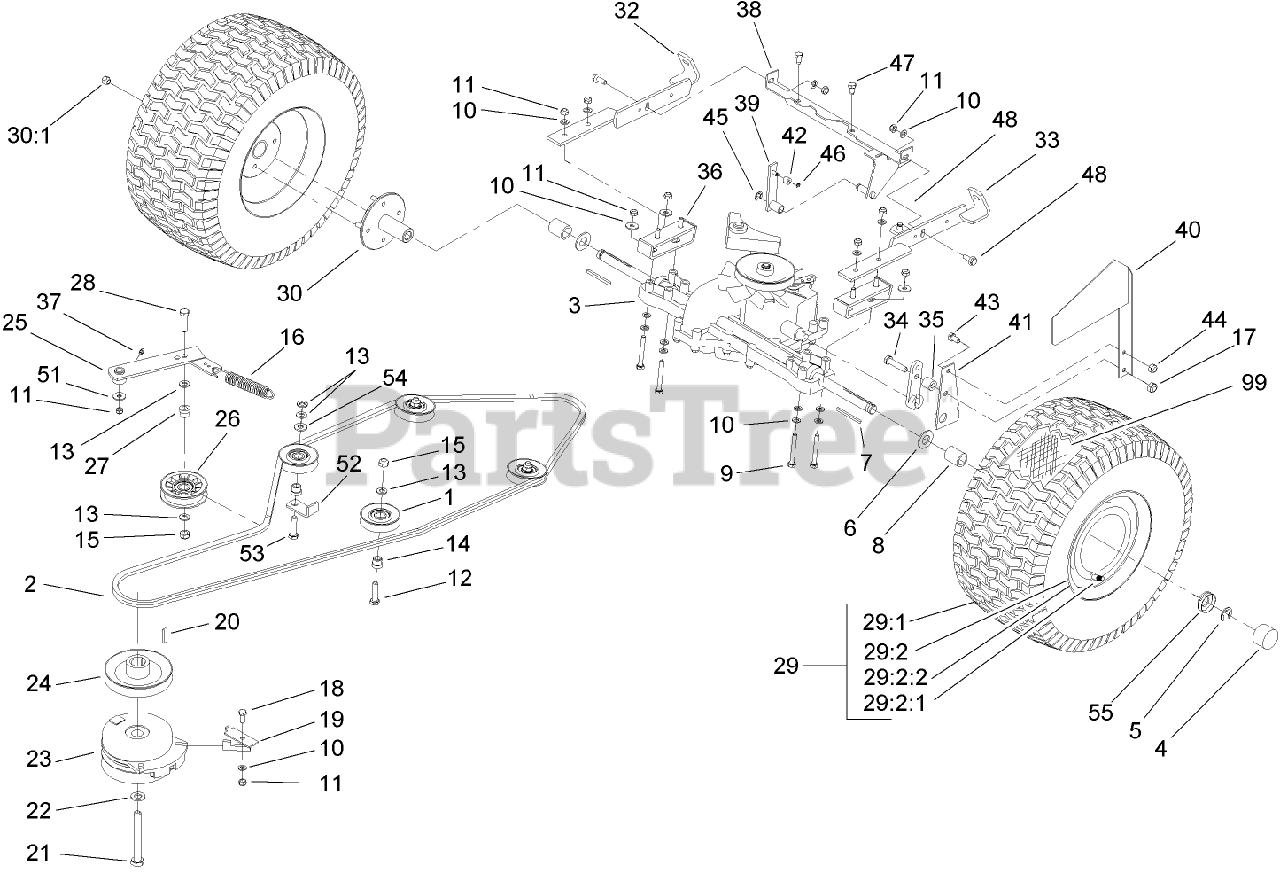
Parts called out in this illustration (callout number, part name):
1	PULLEY-IDLER
2	V-BELT-TRACTION
3	TRANSMISSION
4	CAP-HUB
5	CLIP-SPRING
6	WASHER
7	KEY-SQUARE
8	SPACER-AXLE
9	SCREW-HH
10	WASHER-PLAIN
11	NUT-LOCK, NI
12	SCREW-HH
13	WASHER-FLAT
14	BUSHING-IDLER
15	NUT-LOCK, NI
16	SPRING
17	NUT-LOCK, NI
18	SCREW-HH
19	RETAINER
20	KEY-SQUARE
21	SCREW-HH
22	WASHER-SPRING, BELLEVILLE
23	CLUTCH-ELECTRIC
24	PULLEY-ENGINE
25	ARM-IDLER
26	PULLEY-IDLER
27	BUSHING-IDLER
28	SCREW-HH
29	TIRE AND WHEEL ASM
29:2	WHEEL ASM
29:2:1	Rim
29:2:2	Valve-Tire
30	HUB-WHEEL
30:1	NUT-LUG
32	Bracket-Right
33	Bracket-Left
34	SCREW-HH
35	SLEEVE
36	Plate-Reinforcing
37	FITTING-GREASE
38	Bar ASM
40	ARM-CONTROL, CRUISE
42	Roller
43	SCREW-HH
45	Stirrup
46	STIRRUP
47	SCREW-THREAD FORMING
48	SCREW-HEX
51	WASHER-PLAIN
52	RETAINER-BELT
53	SCREW-HH
54	WASHER-FLAT
55	RETAINER-CAP, HUB
